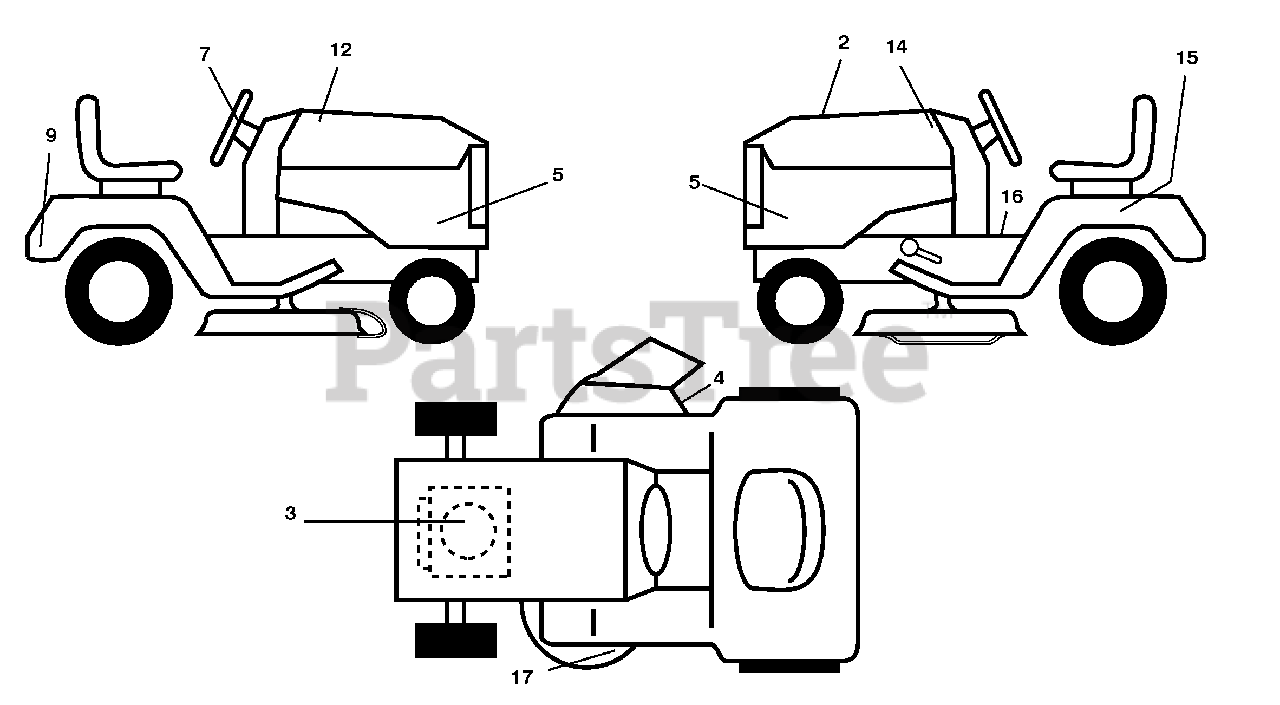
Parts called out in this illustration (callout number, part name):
2	Decal, Replacement
3	Decal, Engine HP
4	Decal, Warning
5	Decal, SDPNL
7	Decal, Ins Str Wh
9	Decal, Fender
12	Decal, Hood RH
14	Decal, Hood LH
15	Decal, Caution, Battery
16	Decal, Fender Warning Eng/Fr
17	Decal, V-Belt Sch.
17	Decal, Handle Lft Height Adj.
17	Manual, Operator's E&F
17	Manual, Parts E&F
